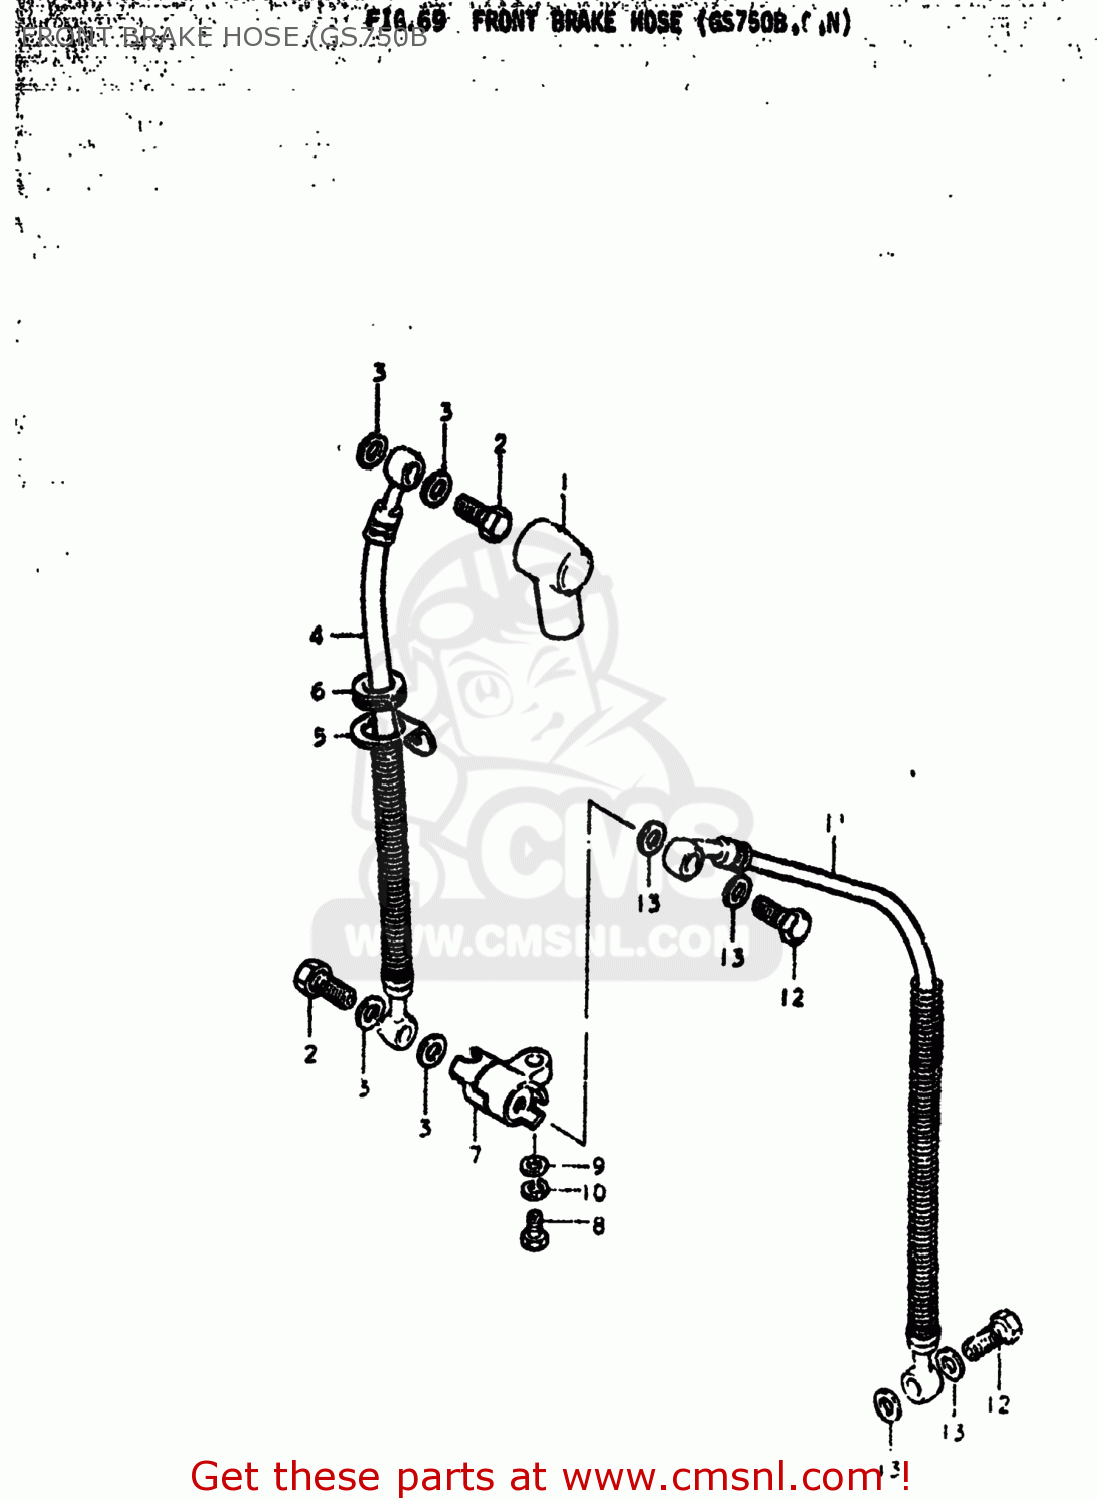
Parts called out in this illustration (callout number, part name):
1	BOOT,MASTER CYLINDER
2	BOLT UNION
3	WASHER
4	HOSE,BRAKE NO.1
5	GUIDE,BRAKE HOSE
6	GROMMET
7	JOINT,BRAKE HOSE
8	BOLT
9	WASHER
10	LOCK WASHER
11	HOSE,FRONT BRAKE
12	BOLT UNION
13	WASHER
